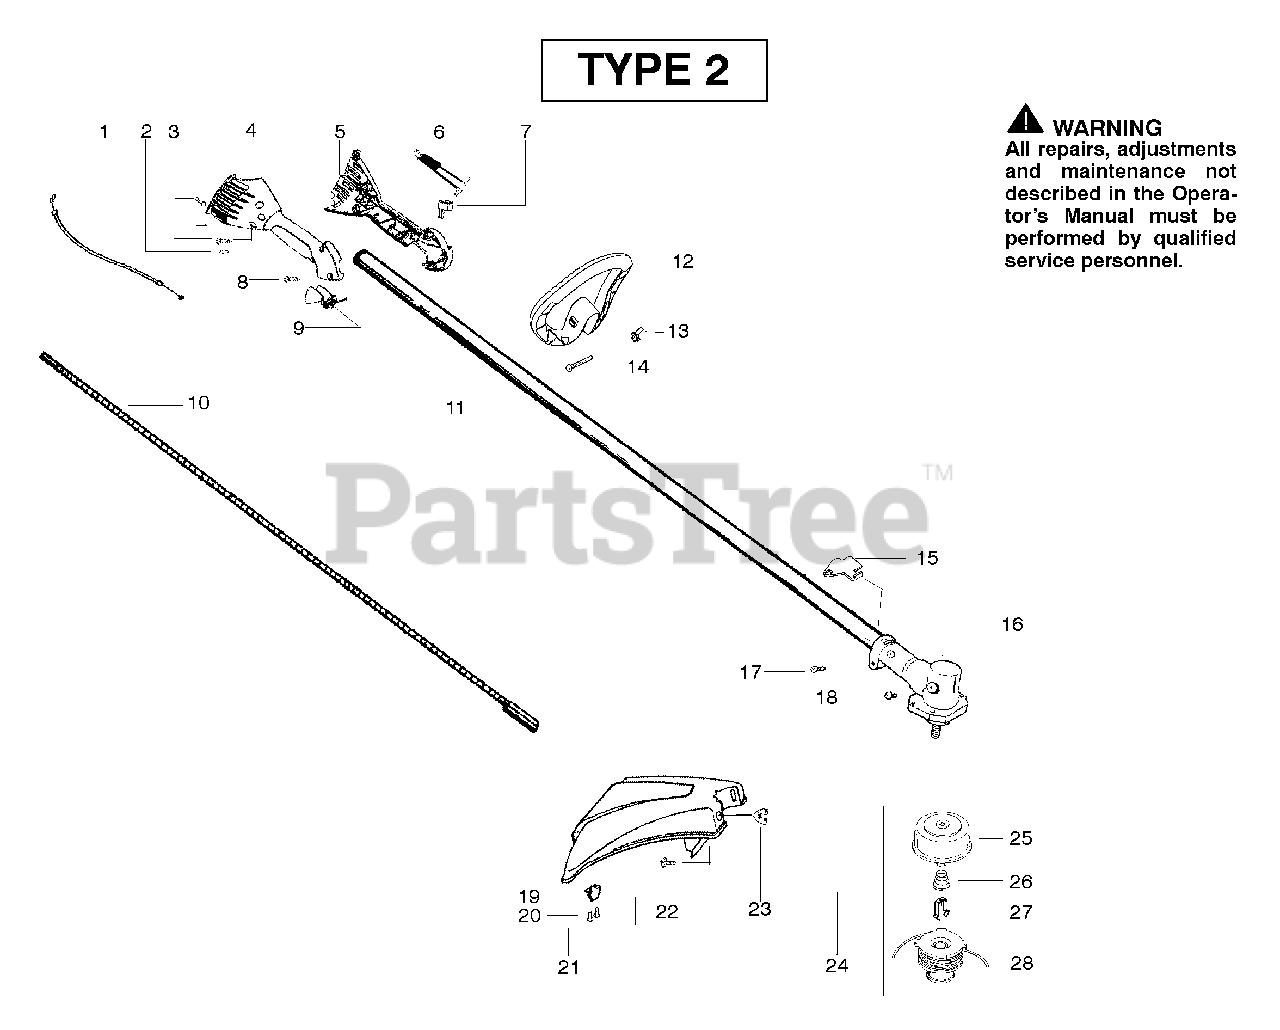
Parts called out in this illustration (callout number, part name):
1	Assy-Throttle cable
2	Screw-alignment
4	Throttle Hsg.-Right
5	Hsg.-Left Throttle
6	Assy-Front wire
7	Kit-Switch
9	Trigger-Throttle
10	Shaft-Flex
11	Assy-Driveshaft
12	Assy-Handle
13	Wingnut
15	Bracket-Shield
16	Assy.-Gearbox non blade
19	Limiter-Line
21	Kit-Shield Ass'y.
23	Wingnut
24	Accy.- Cutting Head
25	Assy.-Hub/Arbor (3/8 lh, 2x)
26	Spring-Return
27	Retainer-Spool
28	Accy.-Wound Spool
